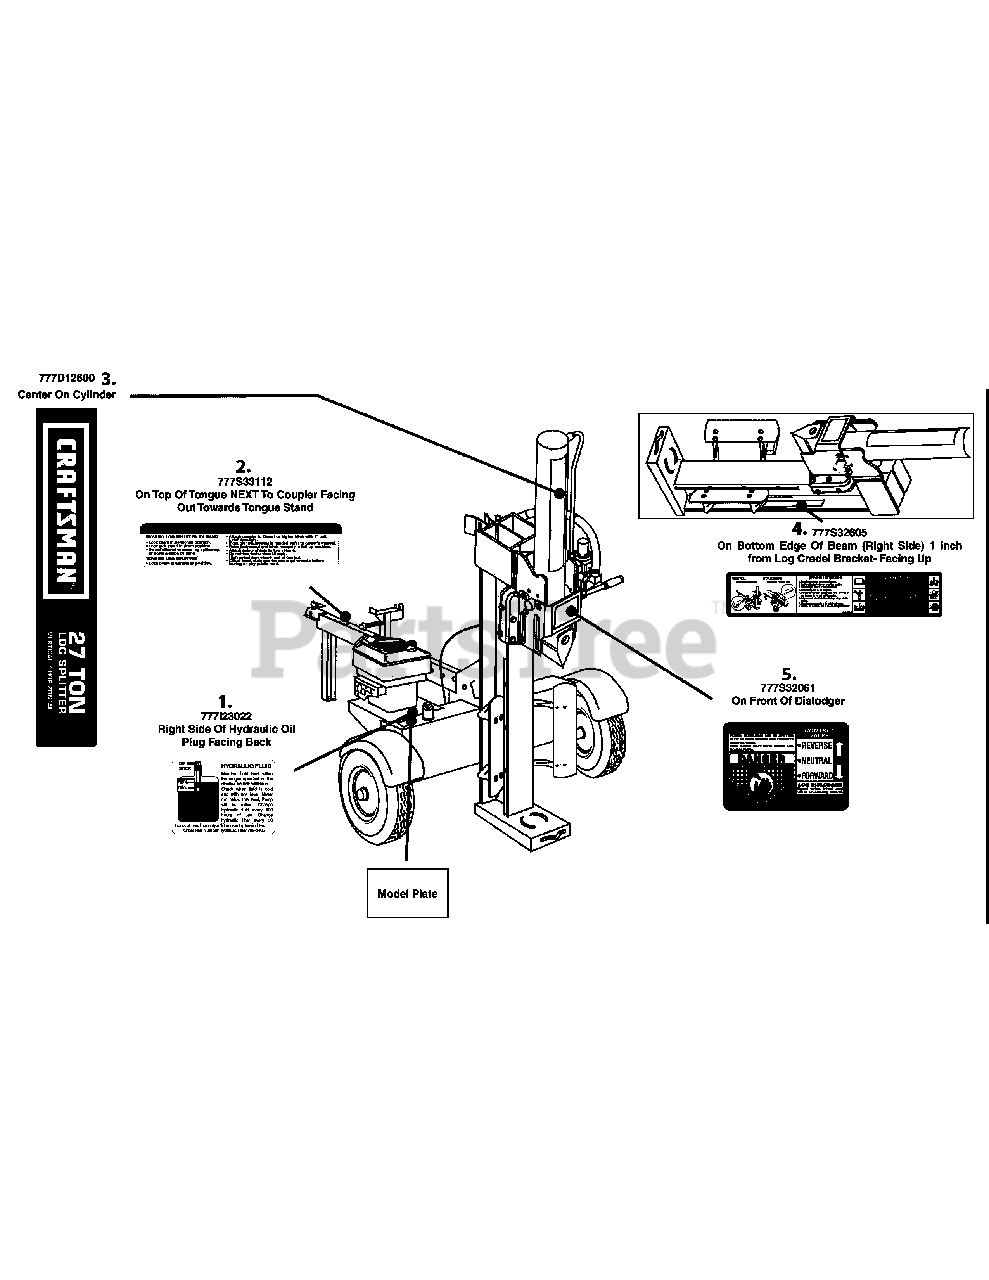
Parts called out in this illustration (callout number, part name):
1	LABEL-LOGSPLITTER HYDRAULIC FLUID
2	LABEL-LOGSPLITTER TOW WARNING
3	LABEL-LOGSPLITTERCYL:CRAFTSMAN 27 T
4	LABEL-BEAM DNGR INSTR
5	LABEL-CNTRL VALVE
